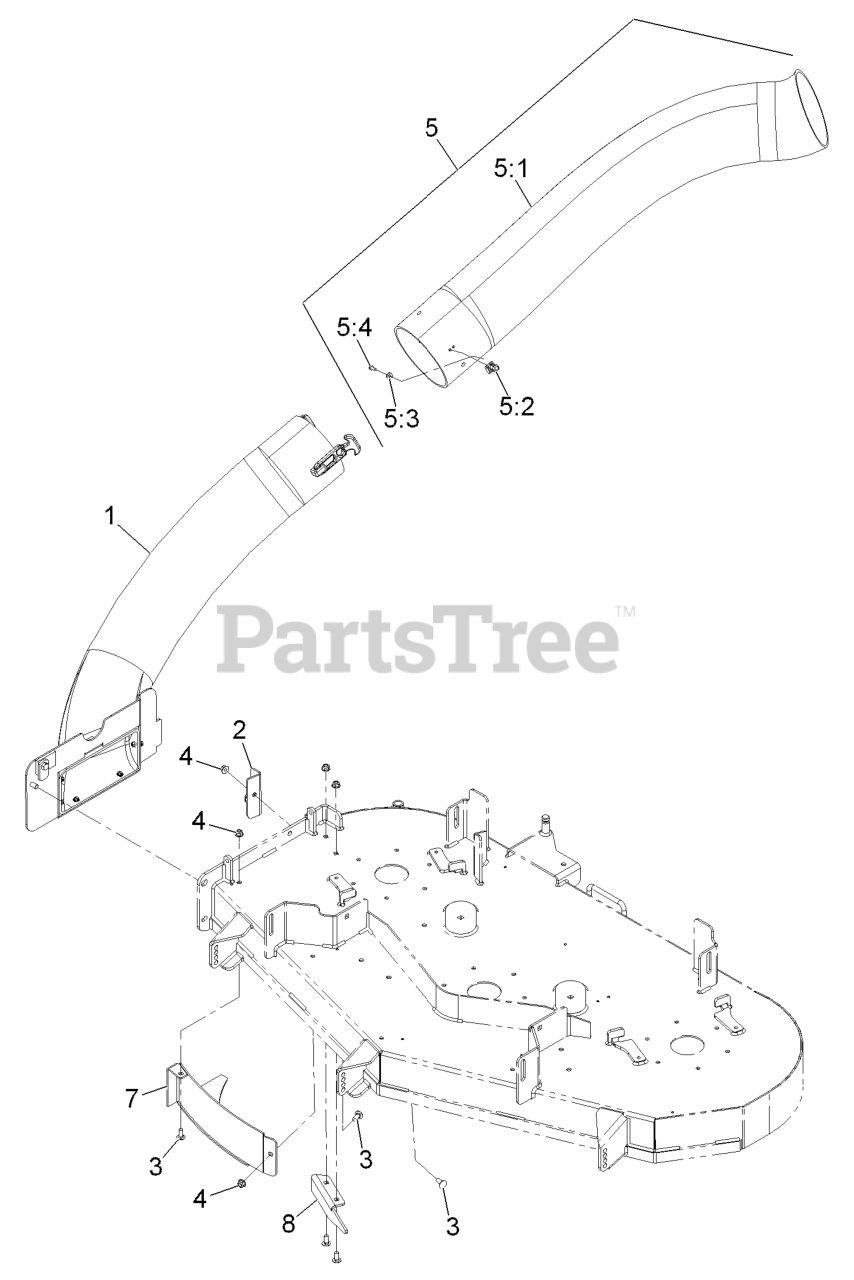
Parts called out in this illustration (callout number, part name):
1	TUBE AND FRAME ASM
2	BRACKET-BOOT MOUNT, 52 IN
2	BRACKET-BOOT MOUNT, 48 IN
3	SCREW-CARR
4	NUT-HF, NI
5	UPPER TUBE W/KEEPER ASM
5:1	TUBE-UPPER
5:2	LATCH-KEEPER
5:3	WASHER-FLAT
5:4	SCREW-PPH
7	WLD,DISCHARGE BAFFLE
8	BAFFLE-DISCHARGE
